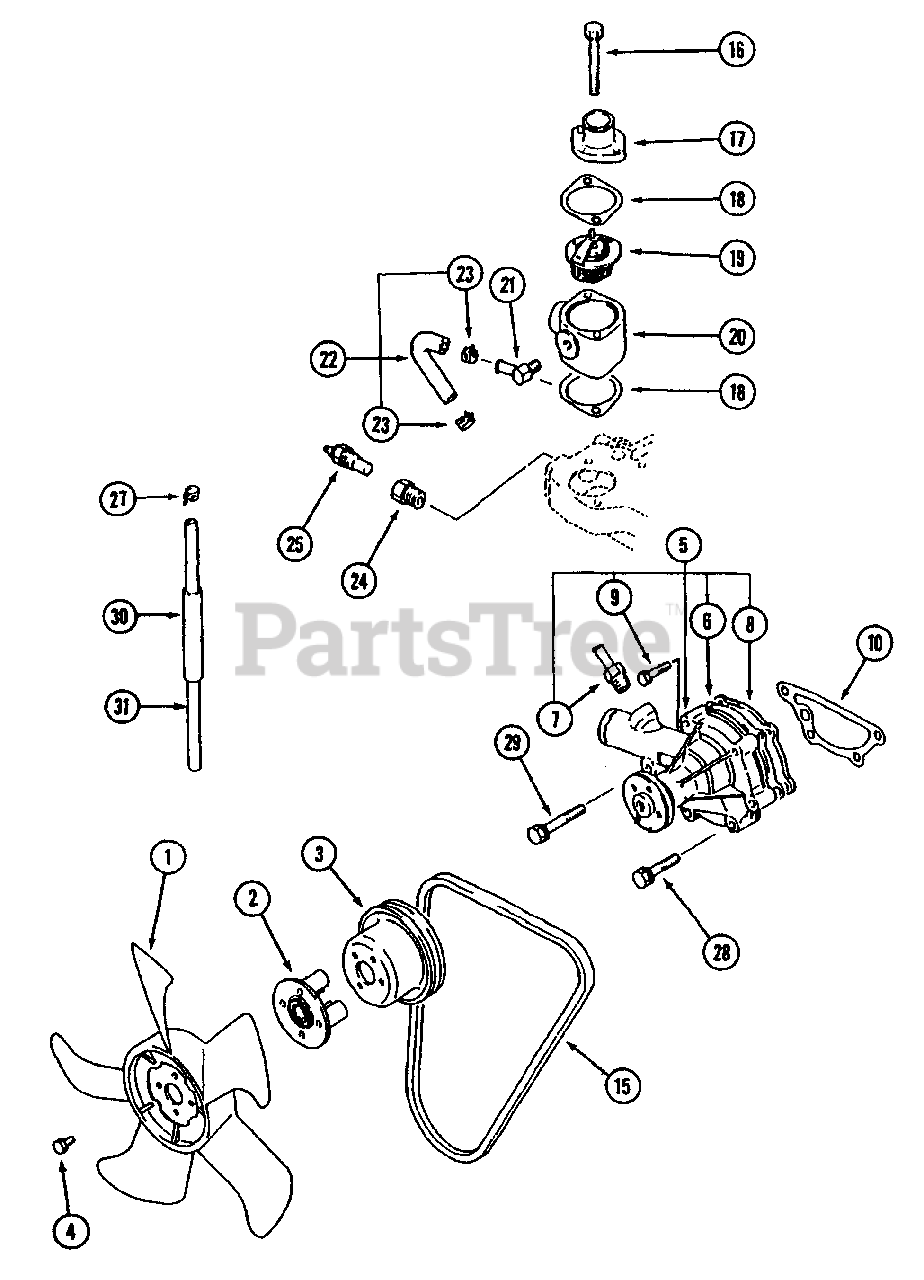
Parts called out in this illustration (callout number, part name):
1	Fan, Cooling
2	Spacer, Fan
3	Pulley, Water Pump
4	Bolt, W/Washer
5	Pump Ass'y., Water
6	Gasket, Water Pump
7	Joint, Water Pump
8	Plate, Water Pump
9	Bolt, W/Washer
10	Gasket, Water Pump
15	V-Belt
16	Bolt, W/Washer
17	Fitting, Water Outlet
18	Gasket
19	Thermostat
20	Fitting, Thermostat
21	Joint, Water Hose
22	Hose Ass'y., Water Bypass
24	Joint, Gauge Unit
25	Gauge Unit, Water Temp
28	Bolt, Washer Ass'y.
29	Bolt, Washer Ass'y.
